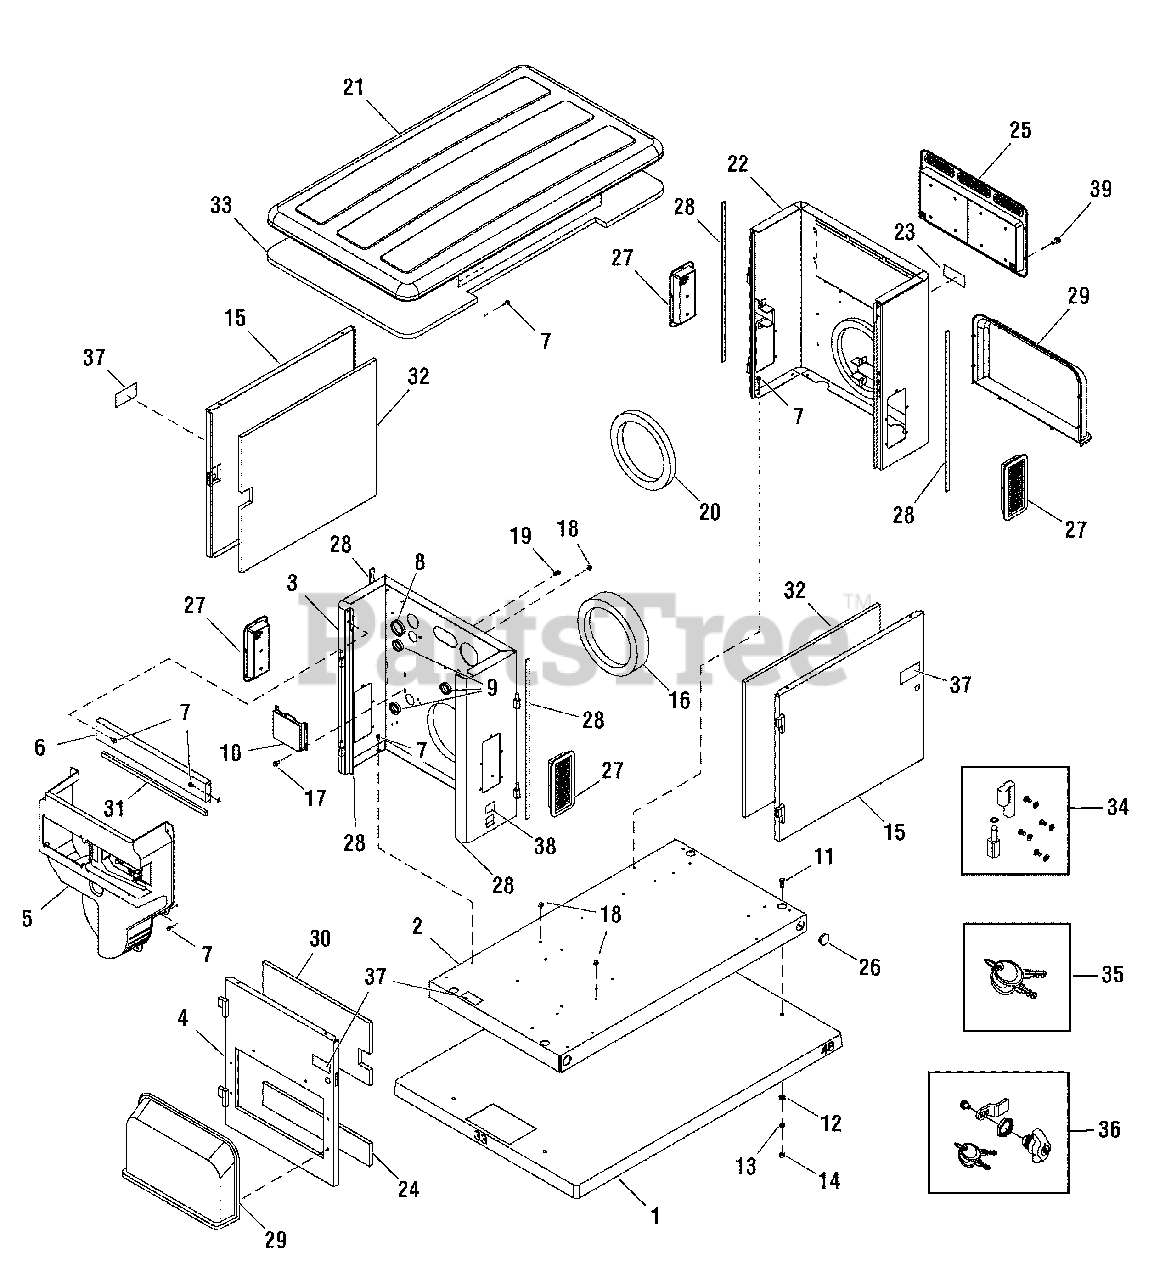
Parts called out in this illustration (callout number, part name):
3	BULKHEAD, Engine
7	BOLT
10	REGULATOR, Voltage
11	* CAPSCREW, Hex Head, 3/8 - 16 x 1
12	* WASHER, Flat, 3/8 - M10
13	* WASHER, Lock, 3/8
14	* NUT, 3/8-16
16	SEAL, Foam
20	SEAL, Foam
22	BULKHEAD, Alternator
24	COVER, Air Intake
29	COVER, Air Intake
